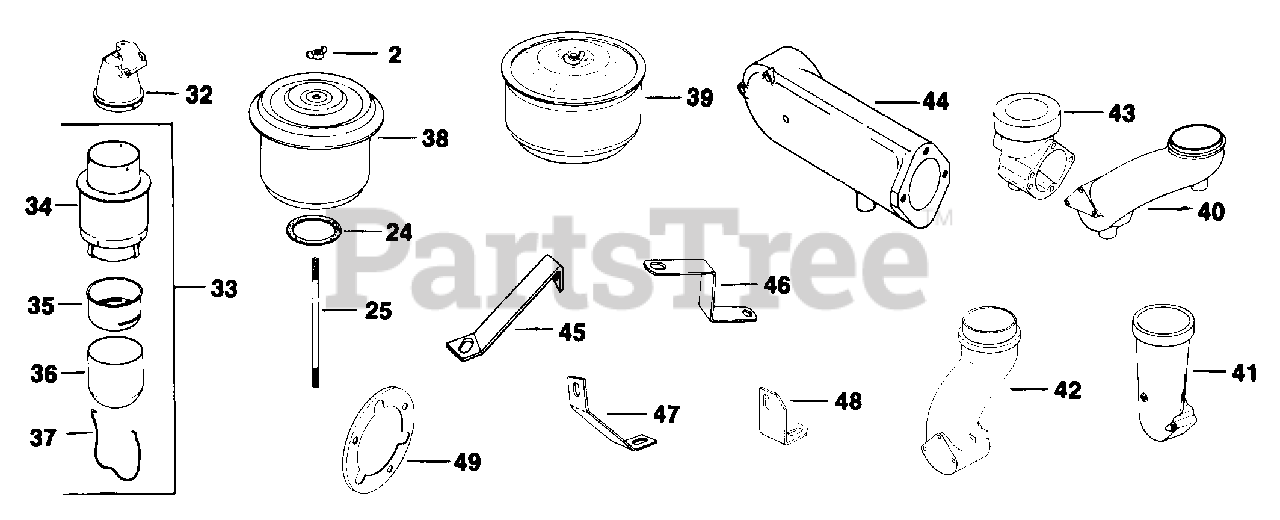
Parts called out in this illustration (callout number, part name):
2	NUT, WING 1/4-20 USE 25 100 15-S
25	STUD - DISCONTINUED
38	CLEANER
40	ADAPTER - DISCONTINUED
47	BRACE, AIR CLEANER - DISC.
